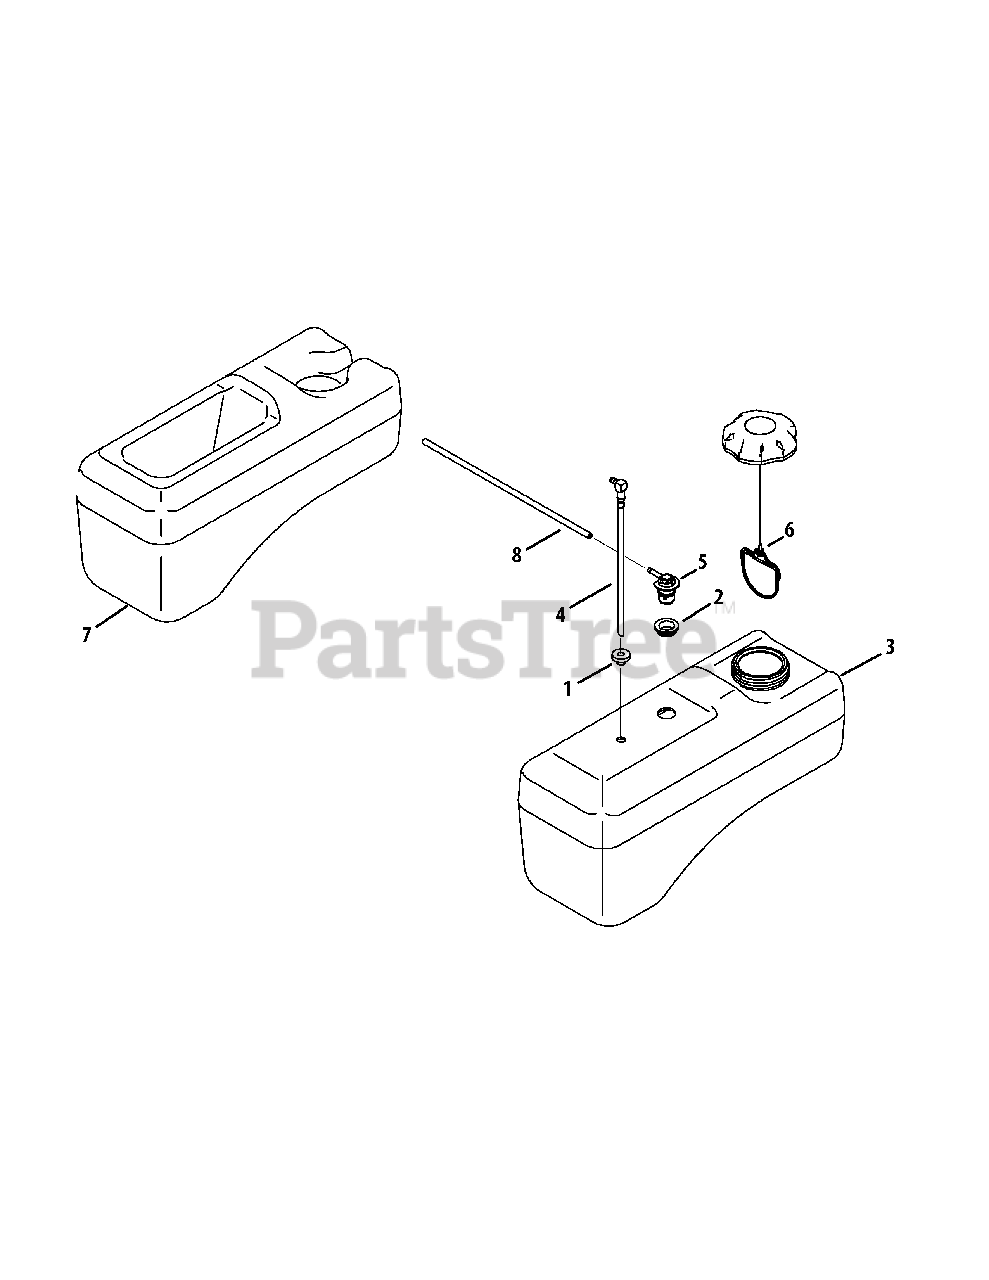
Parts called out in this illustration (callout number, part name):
1	Fuel Tank Bushing
2	Rubber Grommet
4	Fuel Pickup Fitting
5	Rollover Valve
7	Utility Bin
